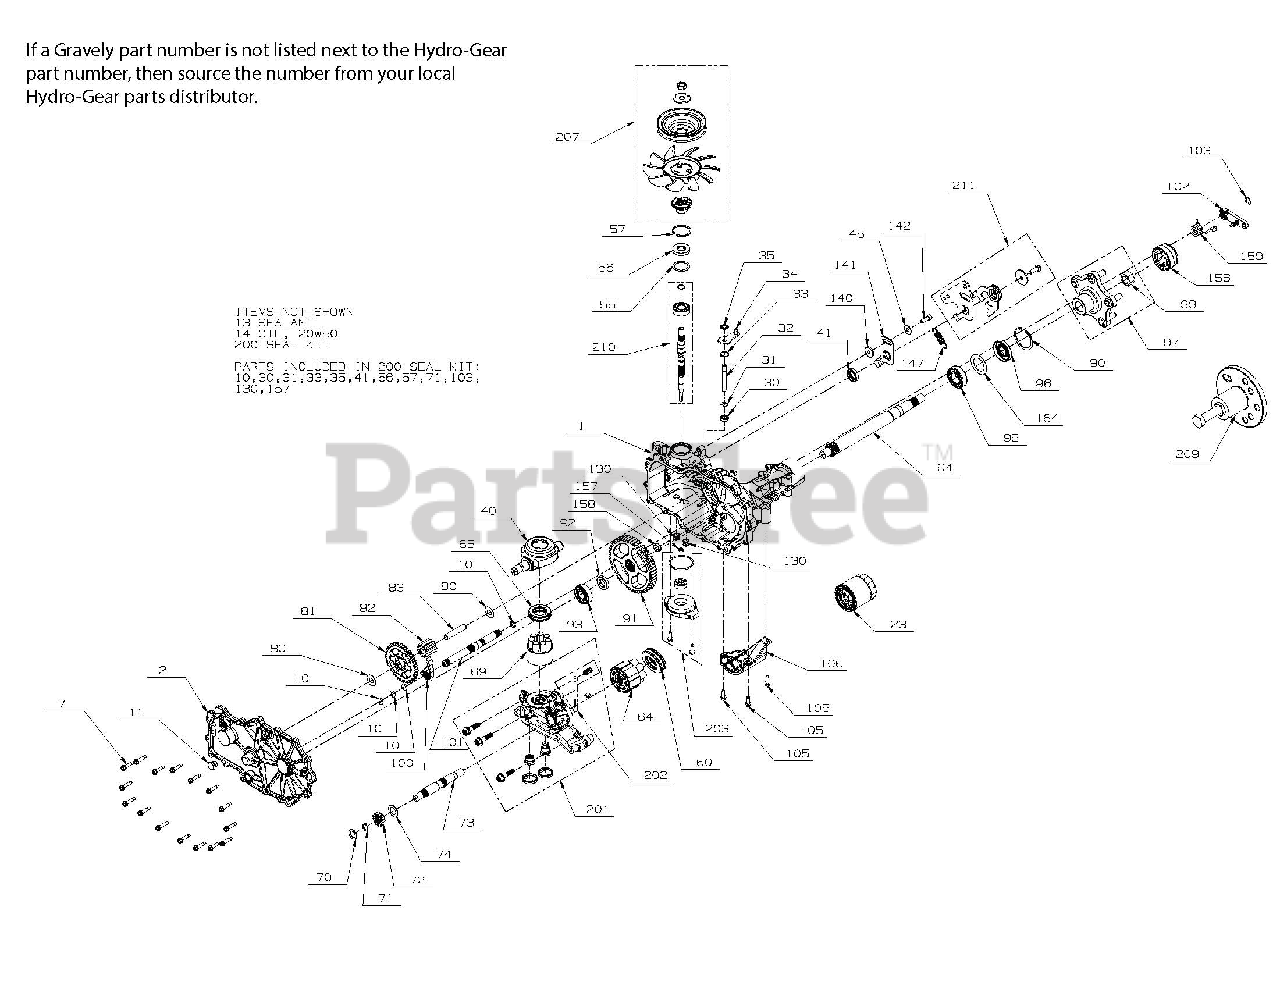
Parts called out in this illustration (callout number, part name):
1	KIT, MAIN HOUSING, RH, CHARGE, CONTROL
2	KIT, SIDE COVER RH
7	SCREW,HEX WASHER 1/4-20X1.125
13	SEALANT
23	OIL FILTER, TRANSMISSION
30	SEAL, LIP .375X.75X.25
31	RING. RETAINING
33	RING, RET .750
34	ARM, BYPASS
35	RING, RTNG .
40	TRUNNION, SWASHPLATE
41	SEAL, LIP 18X32X7
45	WASHER
55	WASHER 1.23X1.56X.04
56	SEAL, LIP 17X40X7
57	RING, RET 1.56 INT
60	HG THRUST BEARING (51462)
64	HG 16CC CYLINDER BLOCK (71579)
65	HG THRUST BLOCK (53502)
69	HG SEVEN PISTON BLOCK (71971)
70	WASHER .63X1.0X.05
71	RING, RET 62 EXT
73	SHAFT, MOTOR
74	WASHER .71 X 1.16 X .04
80	WASHER .5X1.0X.032
83	JACK SHAFT (PIN)
90	RING, RETAINING
93	KIT, BEARING
94	SHAFT, AXLE
95	BEARING, BALL 25.4 X 52 X 15
96	SEAL, LIP
97	HUB, HYDROGEAR P/N 71691
99	NUT, HEX, LOCK 3/4-16
100	PAWL, BRAKE
101	SHAFT, BRAKE
102	KIT, BRAKE ARM RIGHT HAND
105	HFHCS 1/4-20X.75
106	GUARD, FILTER, RH
140	SPACER
141	ARM, NEUTRAL RIGHT
142	SHCS 5/16-24X1 PATCH
147	SPRING, EXTENSION
156	CAP, AXLE
158	MAGNET, RING
159	SPRING, TORSION CCW
164	WASHER, 1.355 x 2.035 x .021 FLAT
200	HG SEAL KIT (71976)
201	KIT, CENTER SECTION RH CHARGE
202	KIT, CHARGE RELIEF
203	KIT, CHARGE PUMP
207	KIT, FAN-PULLEY
209	HUB PULLER 4 BLT HYDGEAR 71459
210	INPUT SHAFT HG 71978
211	KIT, RTN BIDIRECTIONAL
